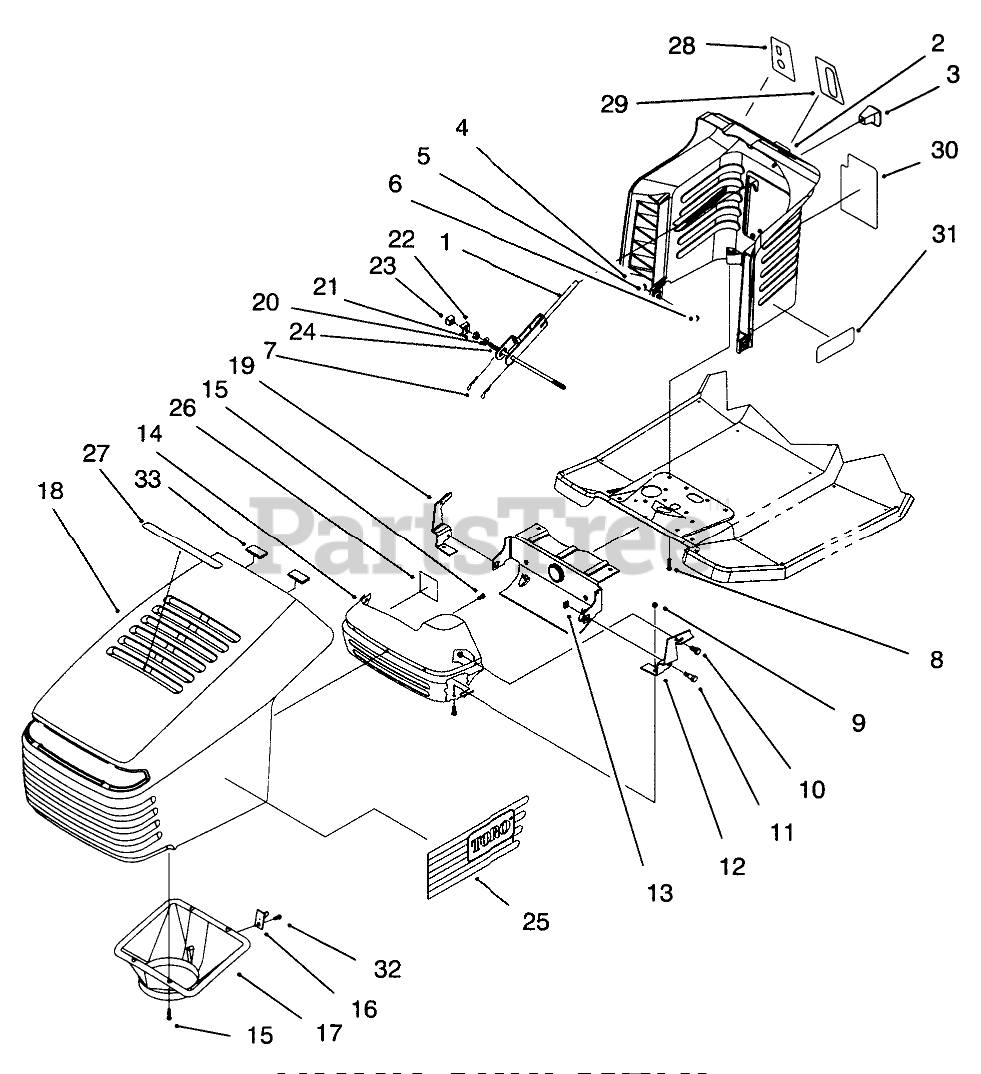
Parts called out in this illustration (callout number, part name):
1	Lever-Deck Engage
2	Tower-Steering
3	KNOB-SHIFT
4	SCREW-HH
5	WASHER-PLAIN
6	NUT-LOCK, NI
7	PIN-COTTER
8	SCREW-HWH
9	NUT-LOCK, NI
10	SCREW-HH
11	BOLT-SHOULDER
12	Bracket-Hinge L.H.
13	NUT-RETAINER
14	Shield-Heat
15	SCREW-PLASTITE
16	LATCH-PIN
17	DUCT-AIR
18	HOOD ASM
19	Bracket-Hinge R.H.
20	WASHER-FLAT
21	NUT-FLANGE
22	ROD-CLAMP PIVOT
23	NUT-WEDGE
24	ROD-TOWER PIVOT
25	DECAL - HOOD LEFT
26	TAPE-FOIL
27	DECAL-AIR DUCT
28	DECAL - IGNITION
29	DECAL
30	DECAL-DECK, ENGAGE
31	DECAL-1232XL
32	SCREW-HWH
33	FOAM-HOOD
